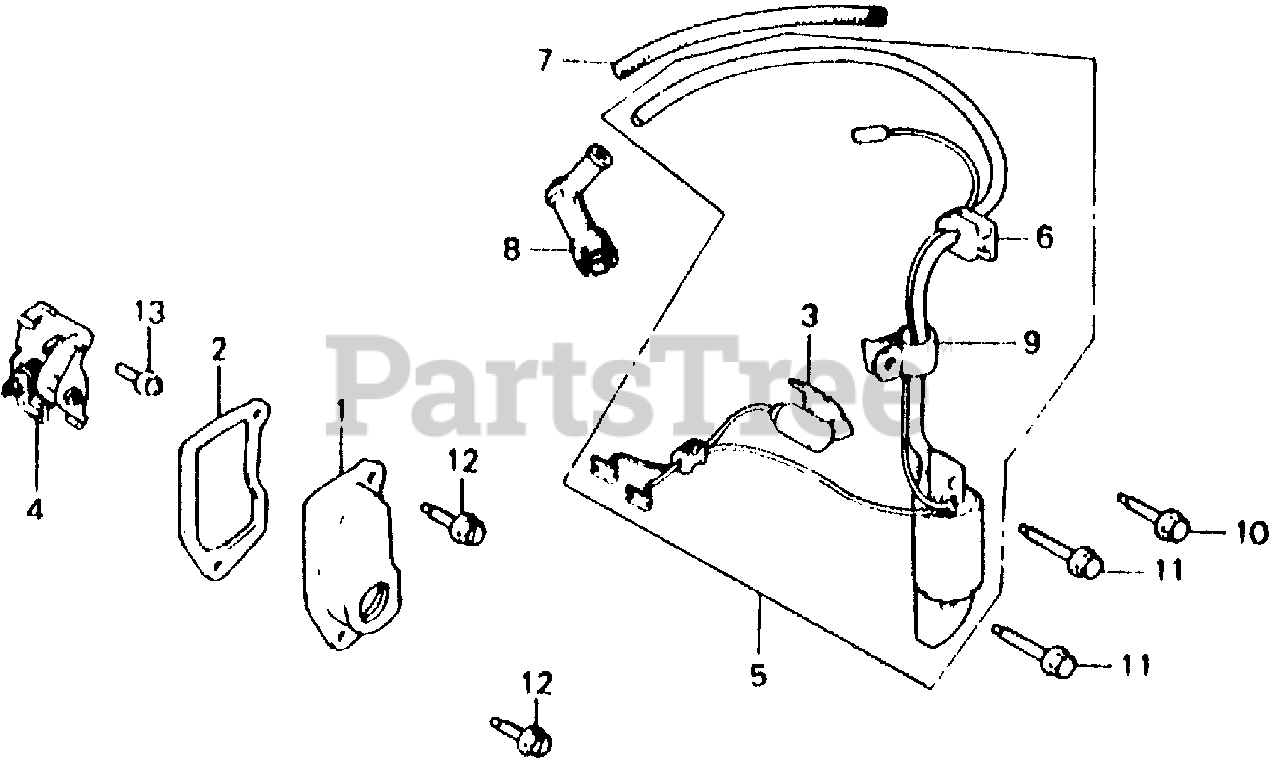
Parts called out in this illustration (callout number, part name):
1	COVER, POINTS
2	GASKET, COVER
3	CONDENSER
4	POINTS ASSY.
5	COIL ASSY., IGNITION (LAMP COIL)
6	GROMMET, WIRE
7	TUBE, IGNITION RUBBER
8	CAP ASSY., NOISE SUPPRESSOR
9	CLAMP, IGNITION WIRE
10	BOLT, FLANGE (6X12) (CT200)
11	BOLT, FLANGE (6X32)
12	BOLT, FLANGE (5X10)
13	SCREW-WASHER (5X12)
